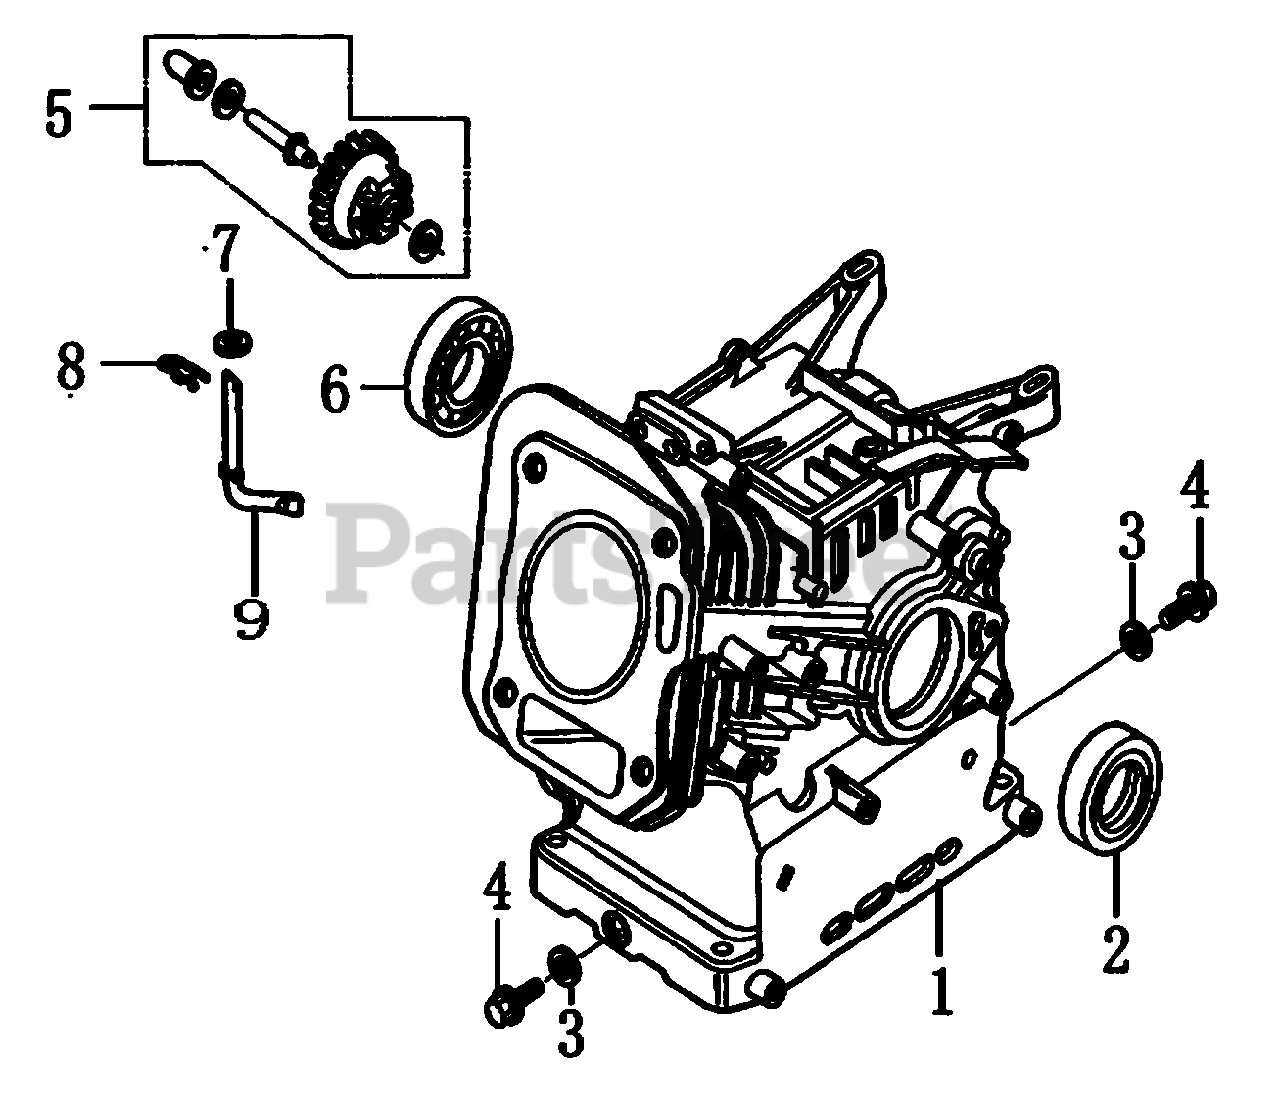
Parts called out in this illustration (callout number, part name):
1	CRANK CASE
2	SEAL, OIL
3	WASHER, DRAIN PLUG
4	BOLT, DRAIN PLUG
5	GOVERNOR GEAR ASSY.
6	BEARING, RADIAL BALL
7	WASHER, PLAIN
8	PIN, LOCK
9	SHAFT, GOVERNOR ARM
